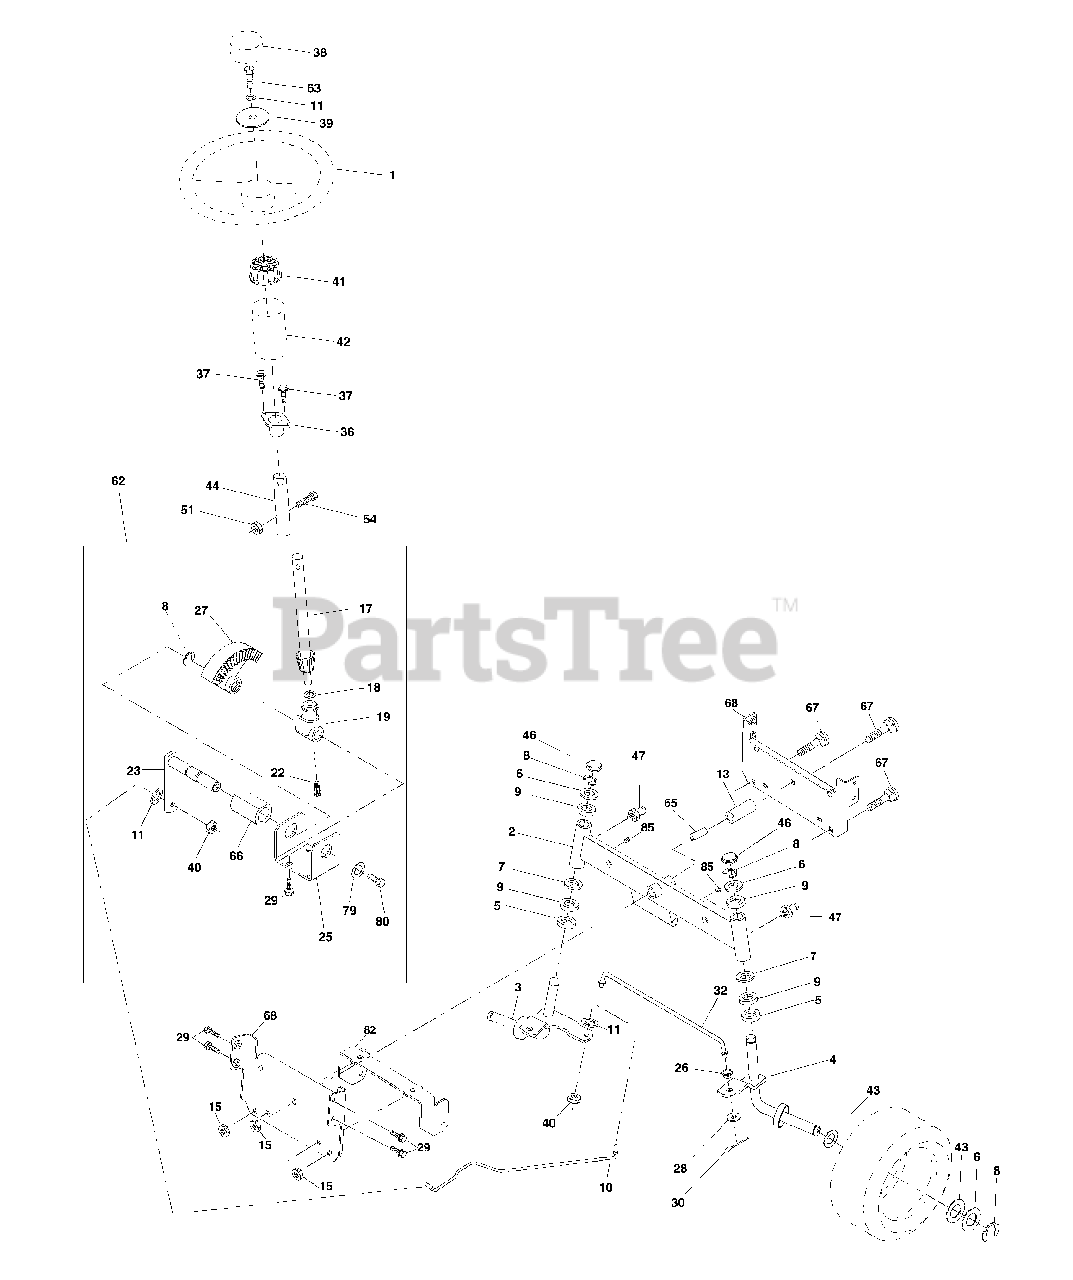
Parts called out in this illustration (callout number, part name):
1	Wheel Steering Ayp/P/L Blk
2	Axle Asm
3	Spindle Asm LH
4	Spindle Asm RH
5	Bearing Race Thrust Harden
6	Washer 25/32 X 1-5/8 X 16 Ga
7	Washer 27/32 X 1-1/4 X 16 Ga
8	Ring Klip #t5304-75
9	Bearing Col Strg Blk
10	Link Drag
11	Washer Lock Hvy Hlcl Spr 3/8
13	Spacer earing Axle Front
15	Hexflange Lock
17	Shaft Asm Strg
18	Washer Thrust 515x 750x 033
19	Support Shaft
22	Screw Hex Wsh Hd Torx
23	Shaft Asm Pittman
25	Bracket Steering
26	Bushing Link Drag Blk LR
27	Gear Sector
28	Washer 13/32 X 7/8 X 16 Ga
29	Screw 3/8-16 x 3/4
30	Pin Cotter 1/8 X 3/4 Cad
32	Rod Tie Wire Form 19 75 Mech
36	Bushing Strg 5/8 Id Dash
37	Screw
38	Cap Wheel Steer Ayp
40	Nut Lock Center 3/8-24un
41	Adaptor Wheel Strg
42	Boot Dash Mtl Steering Blk
43	Washer 25/32 X 1 1/4 X 16 Ga
44	Extension Steering
46	Cap Spindle Fr Top Blk
47	Fitting Grease
51	Nut Lock Hex W/Ins 5/16-18
54	Bolt Fin Hex 3/8-16unc x 1-1/4
62	Kit Steering Assembly Service
63	Bolt Fin Hex 3/8-16unc x 1 Gr.5
65	Spacer Brace Axle
66	Bearing Arm Pittman
67	Bolt Fin Hex 5/8-11 unc x 2-3/4
68	Brace Axle
79	Washer 13/32 x 1 1/4 x 12 Ga.
80	Bolt Hex 3/8-16 x 3/4
82	Bracket Susp Chassis Front
85	Fastener Christmas Tree
